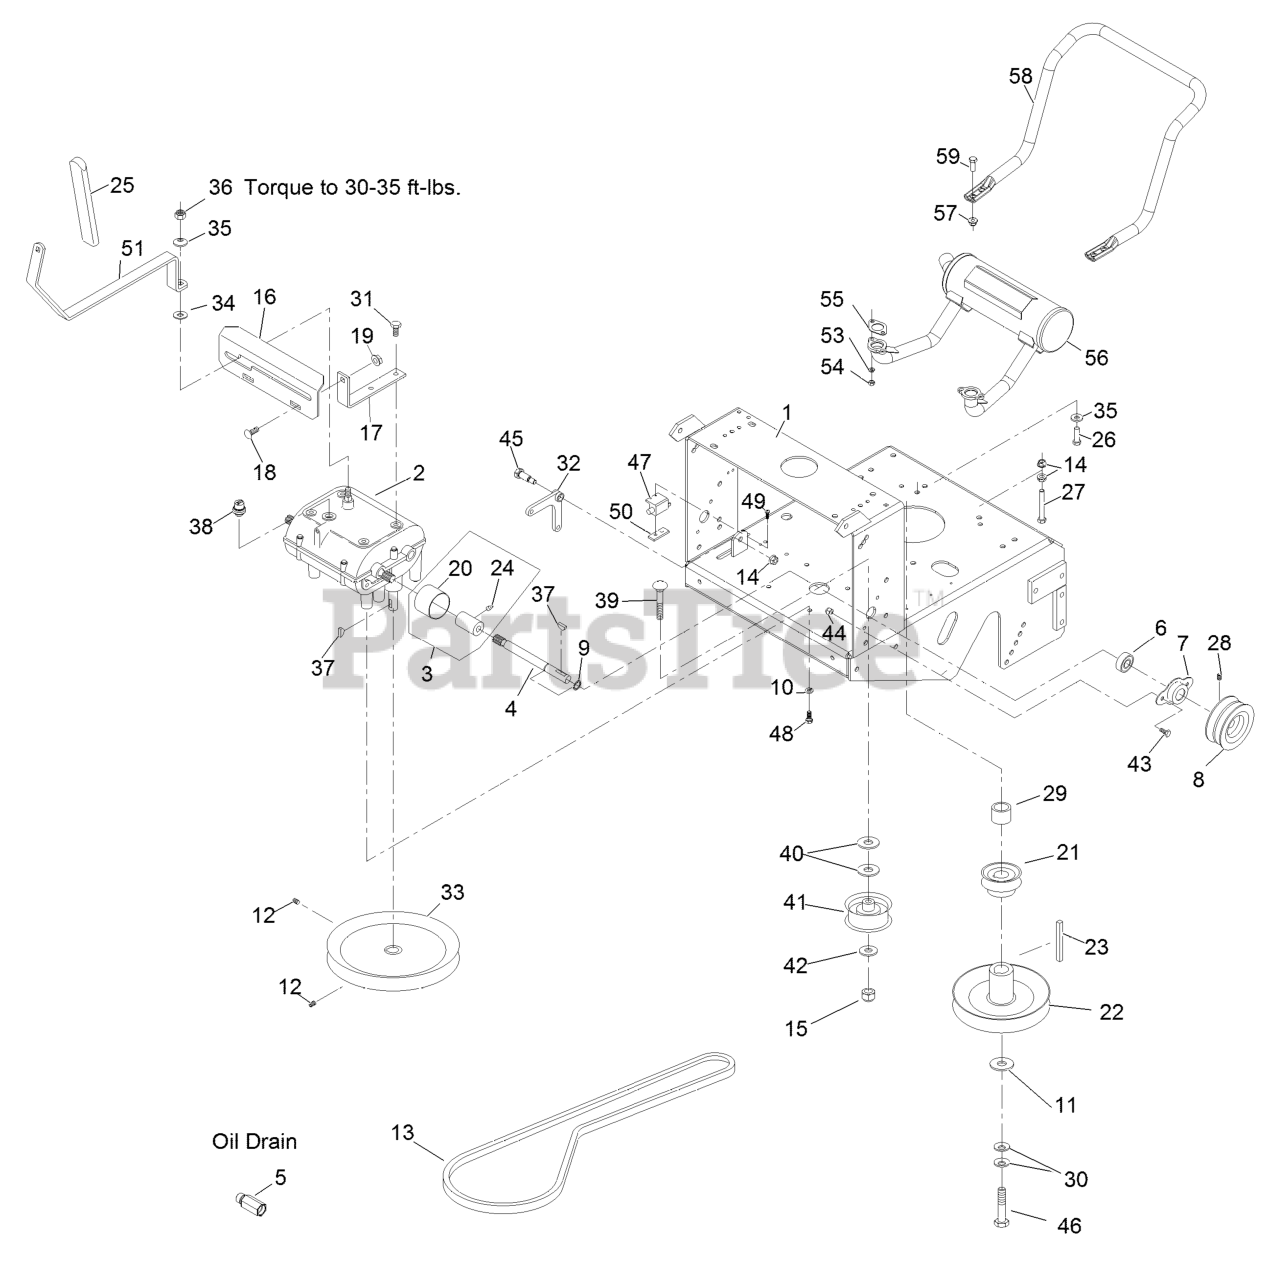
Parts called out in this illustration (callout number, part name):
1	ASM, METRO ENGINE DECK W/
3	ASM,COUPLER/ZERK
4	SHAFT-TRANSMISSION
5	ADAPTER
6	BEARING-SHAFT
7	FLANGE-OUTPUT
8	SHEAVE-TRANSMISSION
9	RING-RETAINING
10	WASHER-LOCK
12	SCREW-HSH
13	BELT,TRANS DRIVE
14	NUT-HHF, WHIZ
15	NUT-LOCK, NI
16	PLATE,SHIFTER W/DECAL
17	BRACKET-PLATE, SHIFT
18	BOLT-CARR
20	GUARD-COUPLER
21	SHEAVE-TRANSMISSION
24	FITTING-GREASE
25	GRIP,FOAM
26	SCREW-HH
27	SCREW-HH
28	SETSCREW
29	SPACER-CLUTCH
30	WASHER-SPRING
31	SCREW-HWH, THREAD CUT
32	BELLCRANK
33	SHEAVE-TRANSMISSION
35	WASHER-BELLEVILLE
36	NUT-LOCK
37	KEY-WOODRUFF
38	SWITCH-START, NEUTRAL
39	SCREW-HH
40	WASHER-FLAT
42	WASHER-FLAT
43	SCREW-HH
44	NUT-LOCK, NI
45	BOLT-SHOULDER
46	SCREW-HH
47	SWITCH-OPEN, NORMALLY
48	SCREW-HH
49	SCREW-PPH
50	PLATE-TAPPED
51	ASM,SHIFT LEVER
53	WASHER-LOCK
55	GASKET-EXHAUST
56	MUFFLER-HORIZONTAL, OFFSE
57	NUT-HF, NI
58	GUARD-MUFFLER
59	SCREW-HH
